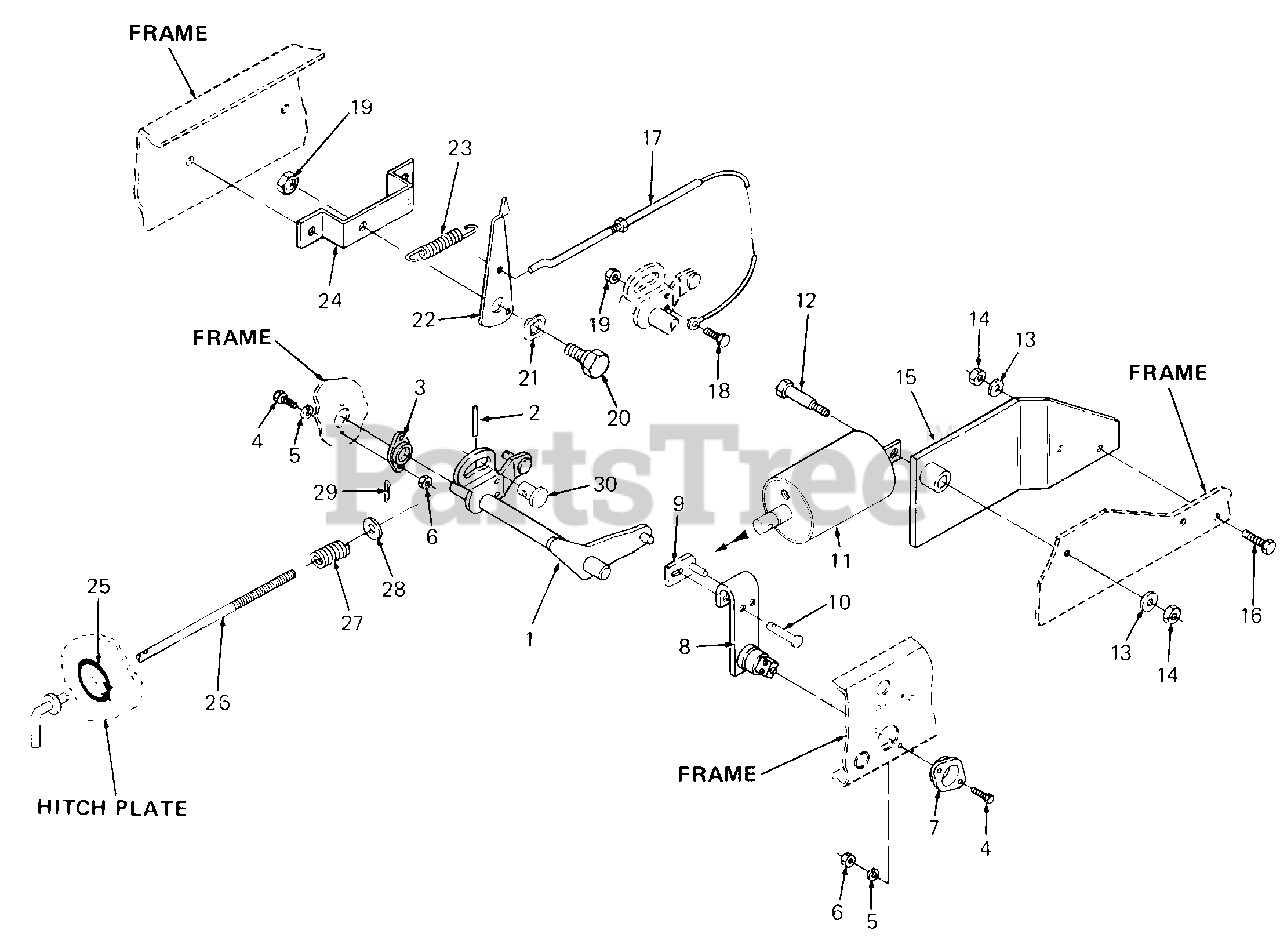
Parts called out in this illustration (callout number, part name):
3	Bushing, Lift, LH
4	Screw, Hex Cap, 1/4-20 X .75 Lg GR5
5	Washer, Lock, 1/4
6	Nut, Hex, 1/4-20 GR5
7	Bushing, Lift, RH
8	Bracket Assy, Lift
9	Pin Assy, Lift
10	Pin, Clevis, 1/2 Dia X 2.172 Lg
11	Cylinder, Hydraulic
12	Bolt, Shoulder
13	Washer, Flat, .531 X 1.06 X .134 Thk
14	Nut, Hex Center Lock, 1/2-13 GR5
15	Bracket, Cylinder
16	Screw, Hex Cap, 1/2-13 X 1.25 Lg GR5
17	Cable Assy, Indicator
18	Screw, Hex Cap, 1/4-20 X .88 Lg
19	Nut, Hex Patch Lock, 1/4-20
20	Screw, Shoulder, .375 Dia X .181
21	Washer, Bowed Spring
22	Arm, Indicator
23	Spring, Extension, .33 OD X 1.12 Lg
24	Bracket, Mounting
25	Graphic, Down Stop Adjustment
26	Rod, Down Stop Adjustment
27	Spring, Compression, .501 X .75 X 1.00 Lg
28	Washer, Flat, .656 X 1.312 X .074 Thk
29	Pin, Internal Cotter
30	Clevis, .750 X 1.00 Lg
